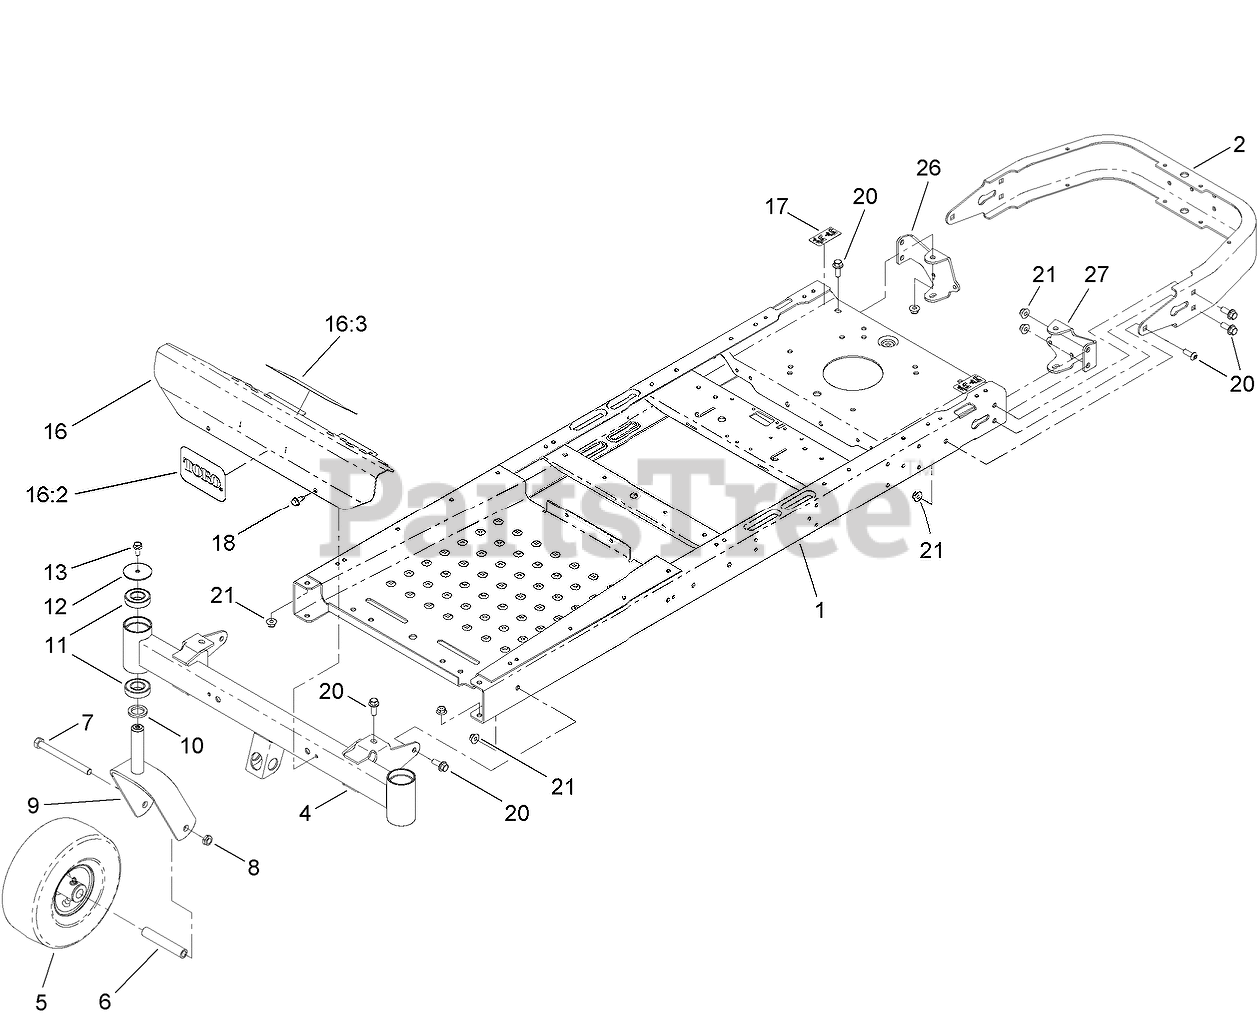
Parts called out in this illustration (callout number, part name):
2	BUMPER-REAR
4	AXLE-FRONT
5	CASTER WHEEL ASM (Cst)
6	BUSHING-SPANNER
7	SCREW-HH
8	NUT-LOCK, NI
9	CASTER FORK ASM
10	WASHER-THRUST
11	BEARING-BALL
12	WASHER
13	SCREW-HHF
16	FOOTREST ASM
16:3	DECAL-DANGER
17	DECAL-BYPASS
18	SCREW-HWHTF
20	SCREW-HHF
20	SCREW-HSBH
21	NUT-HF, NI
26	MOUNT-HYDRO, REAR (RH)
27	MOUNT-HYDRO, REAR (LH)
